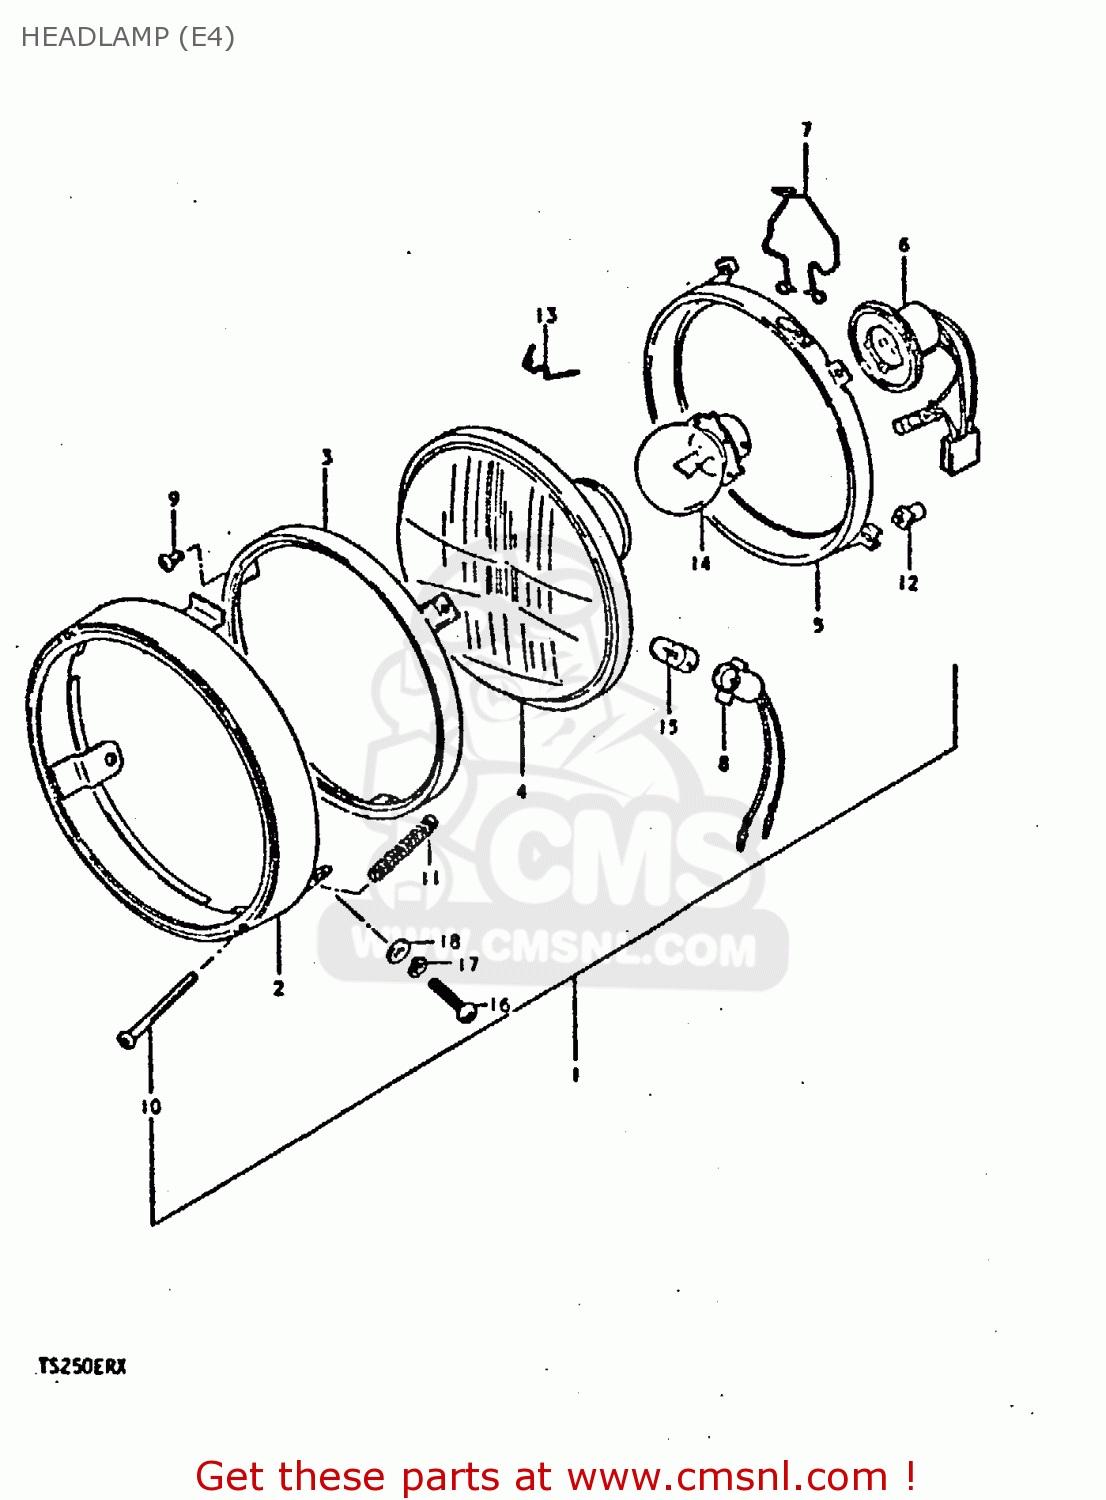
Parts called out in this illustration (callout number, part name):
1	HEADLAMP ASSY
2	RIM
3	RETAINER,HEADLAMP
4	UNIT
5	RING, MOUNTING
6	SOCKET
7	CLAMP,HEADLAMP
8	SOCKET
9	SCREW
10	SCREW,HEADLAMP ADJUST
11	SPRING,ADJUSTING
12	NUT,HEADLAMP ADJUSTER
13	SPRING,HEADLAMP UNIT
14	BULB (6V,25/25W)
15	BULB(6V4W,STANLEY,A1364J)
16	SCREW
17	LOCK WASHER
18	WASHER
